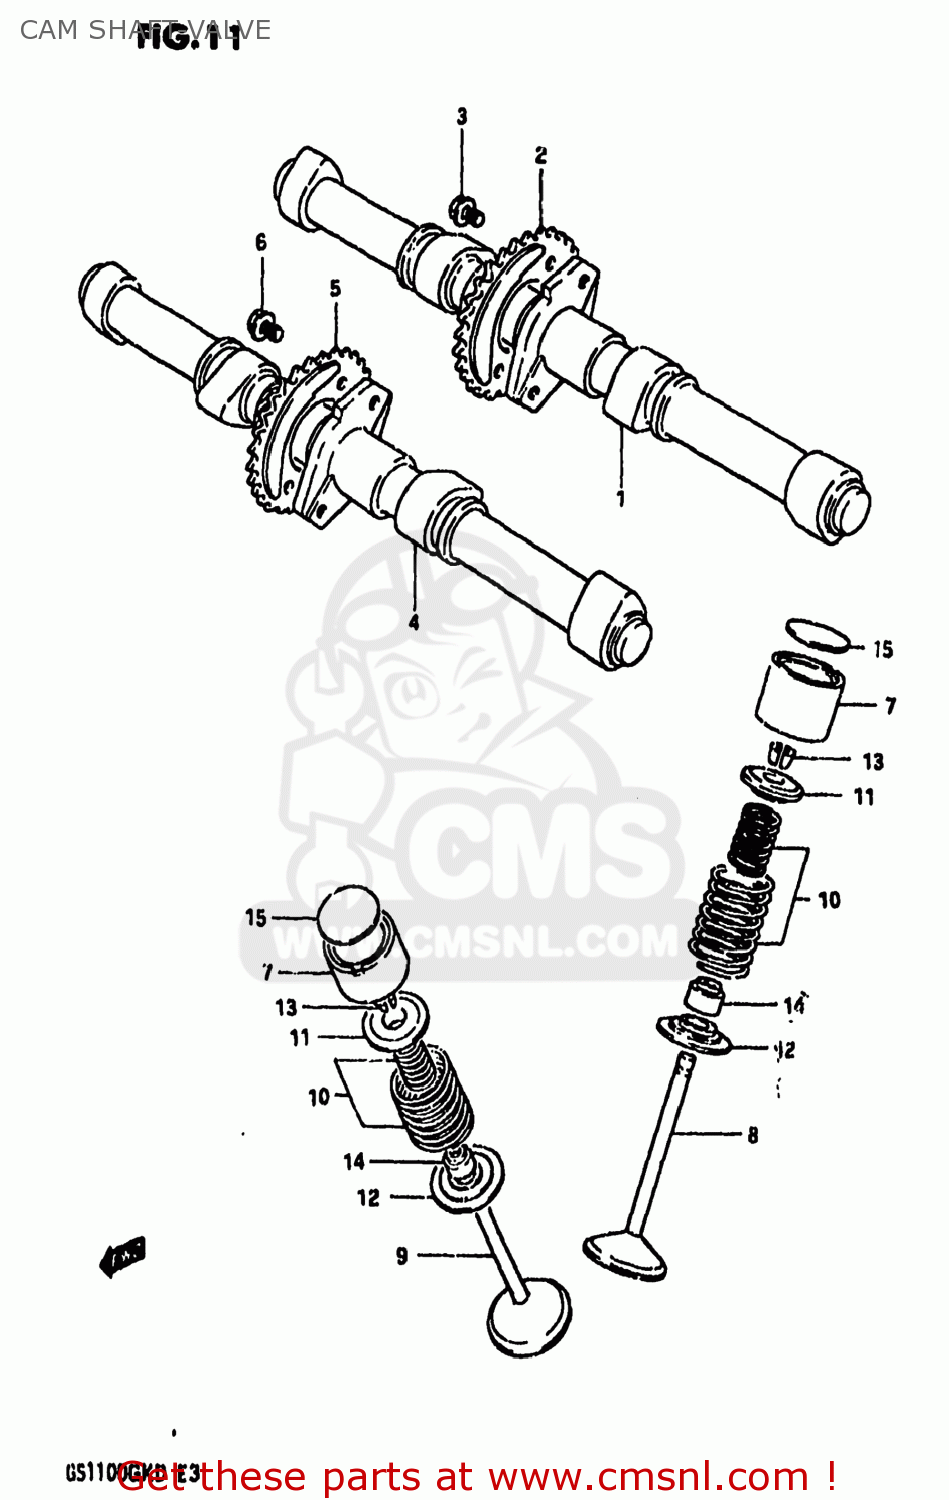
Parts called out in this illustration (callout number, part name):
1	CAMSHAFT,INTAKE
2	SPROCKET,INTAKE CAMSHAFT
3	BOLT(7X11)
4	CAMSHAFT,EXHAUST
5	SPROCKET,EXHAUST CAMSHAFT
6	BOLT(7X11)
7	TAPPET
8	VALVE,INTAKE
9	VALVE,EXHAUST
10	SPRING SET,VALVE
11	RETAINER,VALVE SPRING
12	SEAT,VALVE SPRING
13	COTTER VALVE
14	SEAL,OIL(7X14.4X9)
15	SHIM,TAPPET
16	SHIM SET,TAPPET
17	CASE
